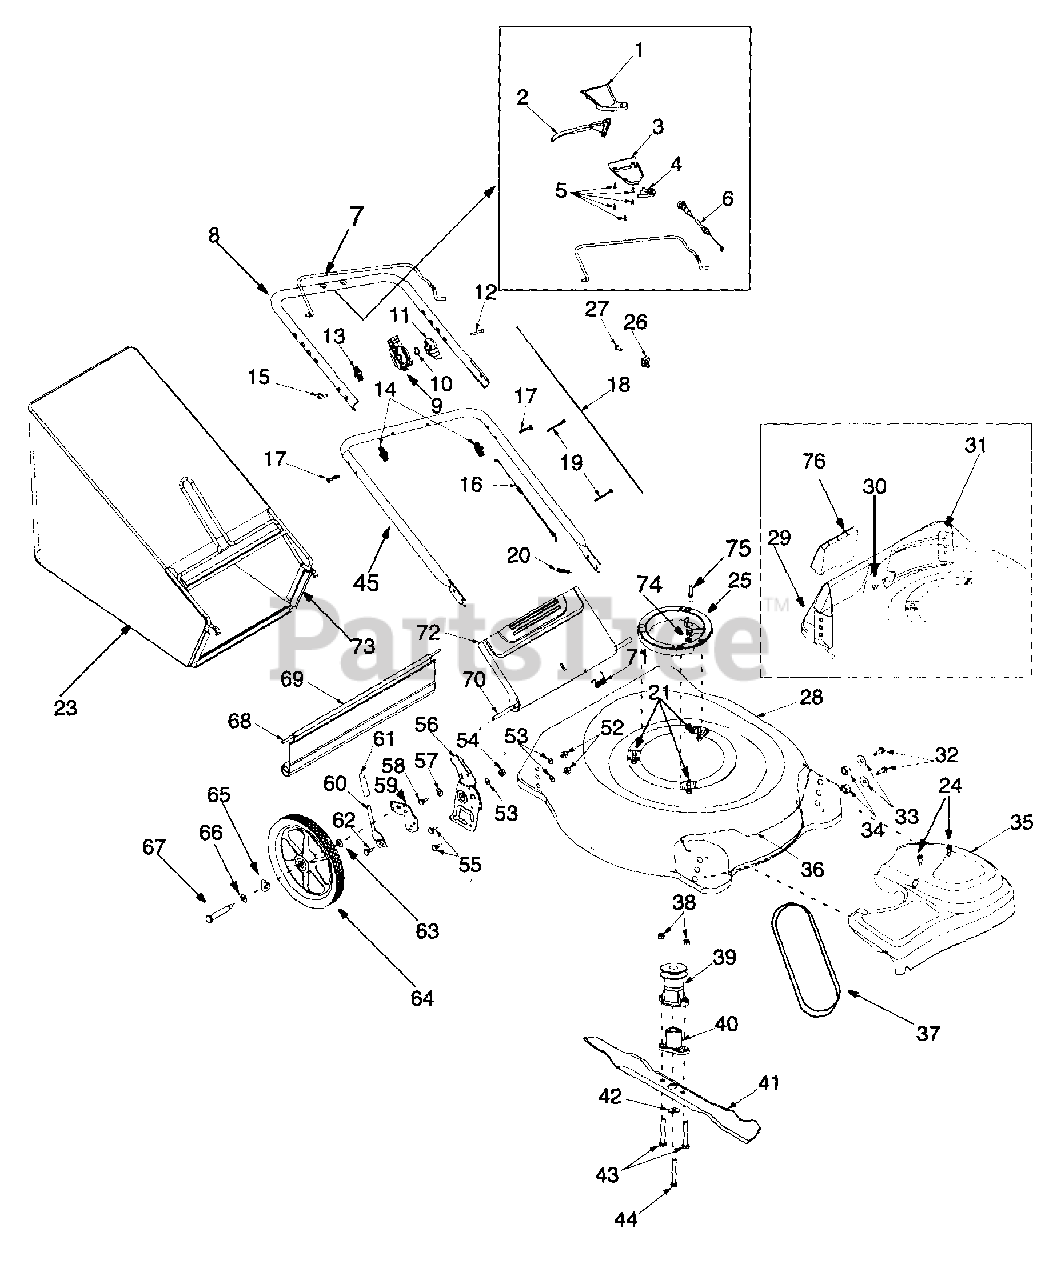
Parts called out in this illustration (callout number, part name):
1	Upper Drive Cover
2	Drive Lever
3	Lower Drive Cover
4	Mounting Cap
5	Screw #10-12 x .75
6	Drive Cable
9	Throttle Housing
10	Curved Washer .663 x .980 x .014
11	Throttle Lever
12	Oval C-Sunk Screw 1/4-20 x 1.81
13	Handle Knob
14	Handle Knob
15	Eye Bolt
16	Throttle Cable: 60"
17	Carriage Bolt 5/16-18 x 2.0
18	Control Cable: 40.5"
19	Cable Tie
20	Cotter Pin
21	TT Screw w/Hex Lock Washer Head
23	Grassbag Assembly
24	Screw #12 x .457
25	Engine Spacer
26	Clamp Casing
27	Hex Screw TT #10-32 x .625
30	Screw AB: 1/4-14: .625
32	Hex Screw 3/8-16 x .75
33	Bell Washer .39 x 1.13 x .062
34	Hex Nut 3/8-16
35	Transmission Cover: Yellow
38	Hex Nut 1/4-20
39	Drive Pulley
40	Blade Adapter
41	Mulching Blade: 21"
42	Flat Washer .516 x 1.5 x .134
43	Hex Screw 1/4-20 x 1.50
44	Hex Screw 3/8-24 x 2.50
52	Hex Nut 3/8-16
53	Bell Washer .39 I.D. x 1.38 O.D.
54	Hex Flange Lock Nut 3/8-16
55	Hex Scr. w/Washer 1/4-14 x .625
57	Bell Washer .265 x .75 x .062
58	Hex Screw TT 1/4-20 x .500
59	Pivot Bar RH
60	Height Adj. Lever
61	Foam Grip
62	Shoulder Scr .500 Dia. x .434
63	Washer .401 x .870 x .063
64	Wheel Assembly: 14 x 2 Yellow Link Trd.
65	Spring Washer .50 I.D. x 1.0 O.D.
66	Flat Washer .510 x 1.373 x .04
67	Shoulder Screw .500 x 2.62 3/8-16
68	Wire
69	Rear Trailing Shield
70	Pivot Rod
71	Torsion Spring
74	Hex Nut
75	Screw
